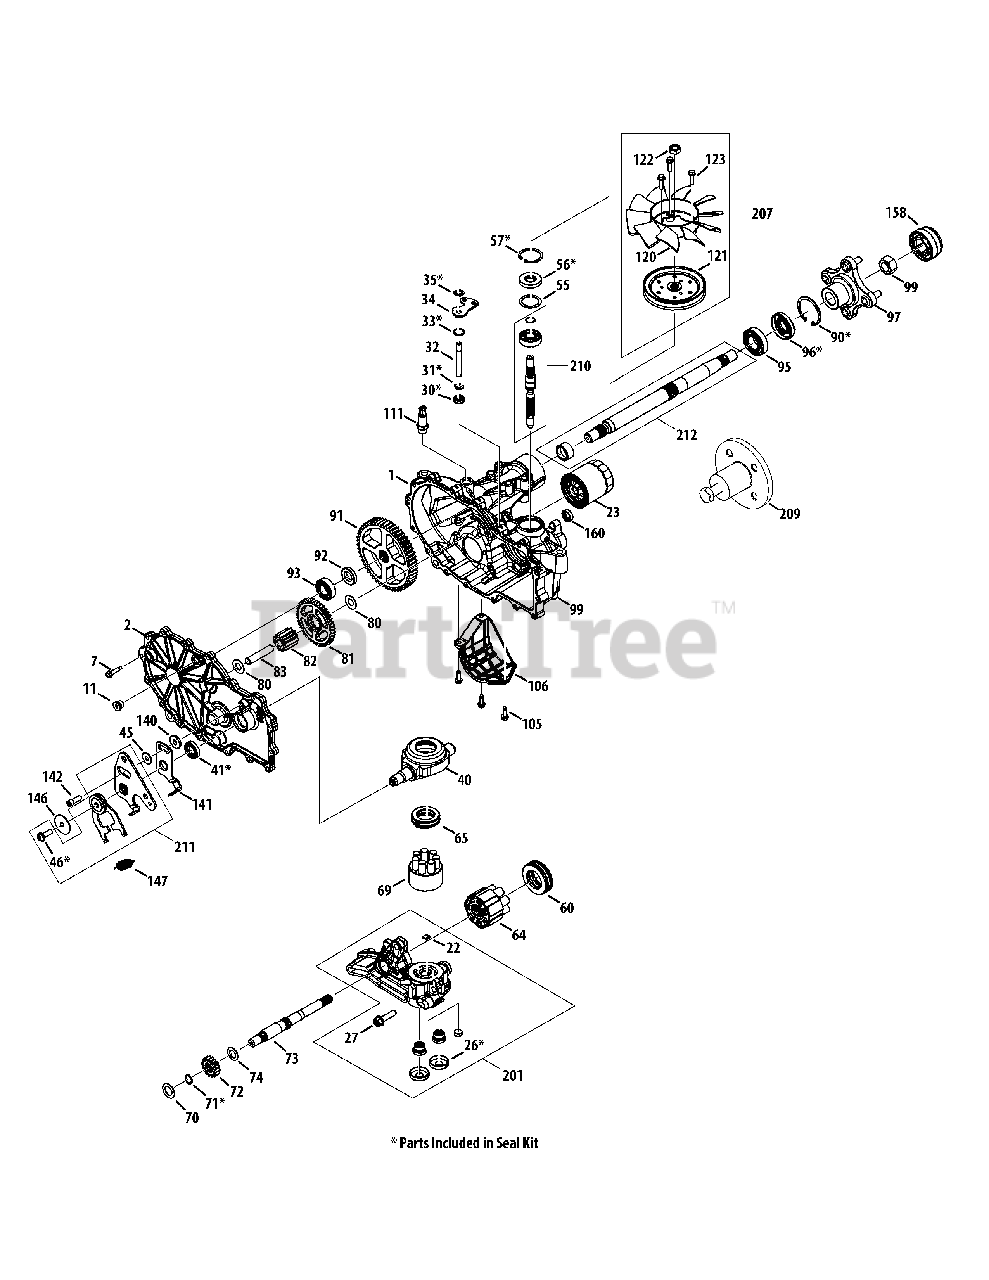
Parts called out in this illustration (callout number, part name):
1	Kit, Housing, Main, LH
2	Kit, Cover, Side, LH
7	Hex Cap Screw, 1/4-20 x 1.125
22	Plate, Bypass
23	Oil Filter, Transmission
26	Seal, Plug, 1.25 x .25
27	Hex Cap Screw, 3/8-16 x 1.5
30	Seal, Lip .375 x .75 x .25
31	Ring, Ret .375 External
32	Rod, Bypass
33	Ring, Ret .75 Internal
34	Arm, Bypass
35	Ring, Retaining .375 External
40	Trunnion, Swashplate
41	Seal, Lip 12 x 32 x 7
45	Washer, .34 x .88 x .06
46	Hex Cap Screw, 5/16-24 x 1.00
55	Washer, 1.23 x 1.56 x .04
56	Seal, Lip 17 x 40 x 7
57	Ring, Retaining
60	Bearing, Thrust
64	Cylinder Block Assembly
65	Thrust Ball Bearing, 30 x 52 x 13
69	Block 7 Piston Assembly
70	Washer, .63 x 1.0 x .05
71	Retaining Ring, .625
72	Gear, 16t
73	Motor Shaft
74	Washer, .72 x 1.16 x .04
80	Washer, .5 x 1.0 x .03
81	Gear, 43t
82	Gear, 11t
83	Jack Shaft
90	Retaining Ring, 2.06 Internal
91	Gear, 54t
92	Spacer, .75 x 1.32 x .257
93	Ball Bearing, .75 x 40 x 12
95	Ball Bearing, 1.0 x 52 x 15
96	Seal, Lip 25 x 52 x 10
97	Kit, Hub, 4 Bolt
99	Nut, 3/4-16, Hex Lock
105	Hex Cap Screw, 1/4-20 x .75
106	Guard, Filter, LH
111	Fitting, 9/16-18 SAE .5 Barb
120	Fan 7", 10 Blade
120	Hub, Fan/Pulley
121	Disc, Pulley
122	Nut, 1/2-20, Hex Jam
123	Hex Cap Screw, 1/4-20 x .875
140	Spacer, .320 x 1.005 x .179
141	Neutral Right Arm
142	Hex Cap Screw, 5/16-24
146	Washer, .343 x 1.5 x .062
147	Extension Spring, .57 x 2"
160	Seal, Lip, .625 x .875 x .25
201	Kit, Center Section, LH
207	Kit, Fan & Pulley
209	Hub Puller, 4 Bolt
210	Kit, Input Shaft
211	Kit, RTN, Bidirectional
212	Kit, Shaft, Axle
